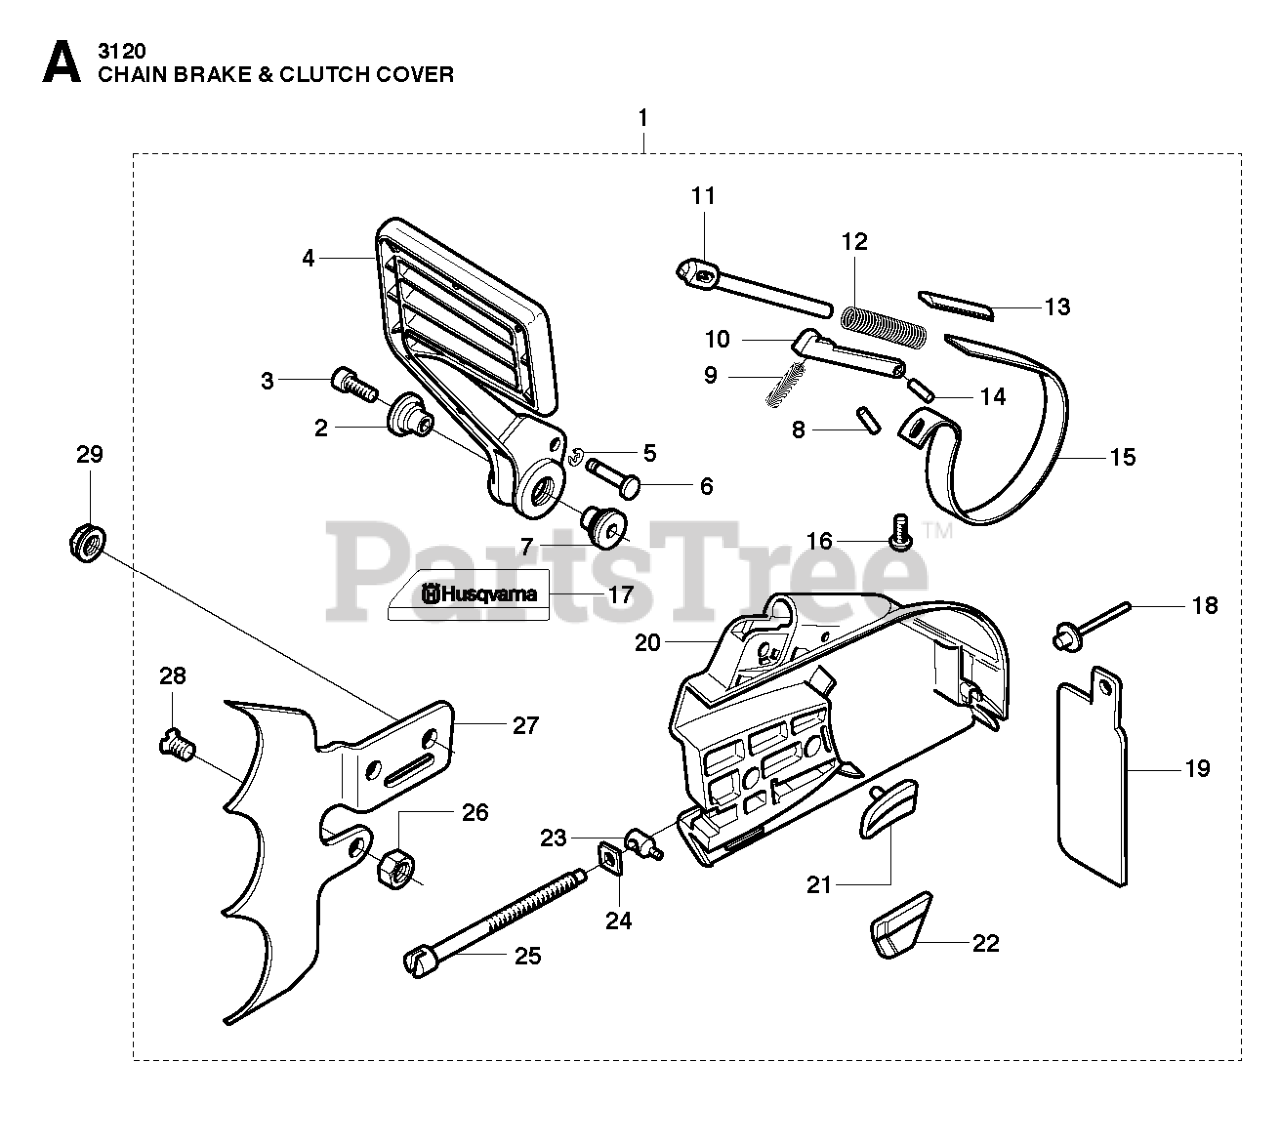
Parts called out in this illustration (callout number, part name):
1	CHAIN BRAKE
2	PIVOT SLEEVE L
7	PIVOT SLEEVE R
14	SPIRAL PIN 4X12
15	BRAKE BAND
16	SCREW
19	DUST GUARD
20	CLUTCH COVER
21	CHAIN GUIDE
22	CHAIN GUIDE
23	PULLER UNIT
27	FELLING DOG
28	SCREW MF6S 6X14
29	NUT M8 FLANGE
